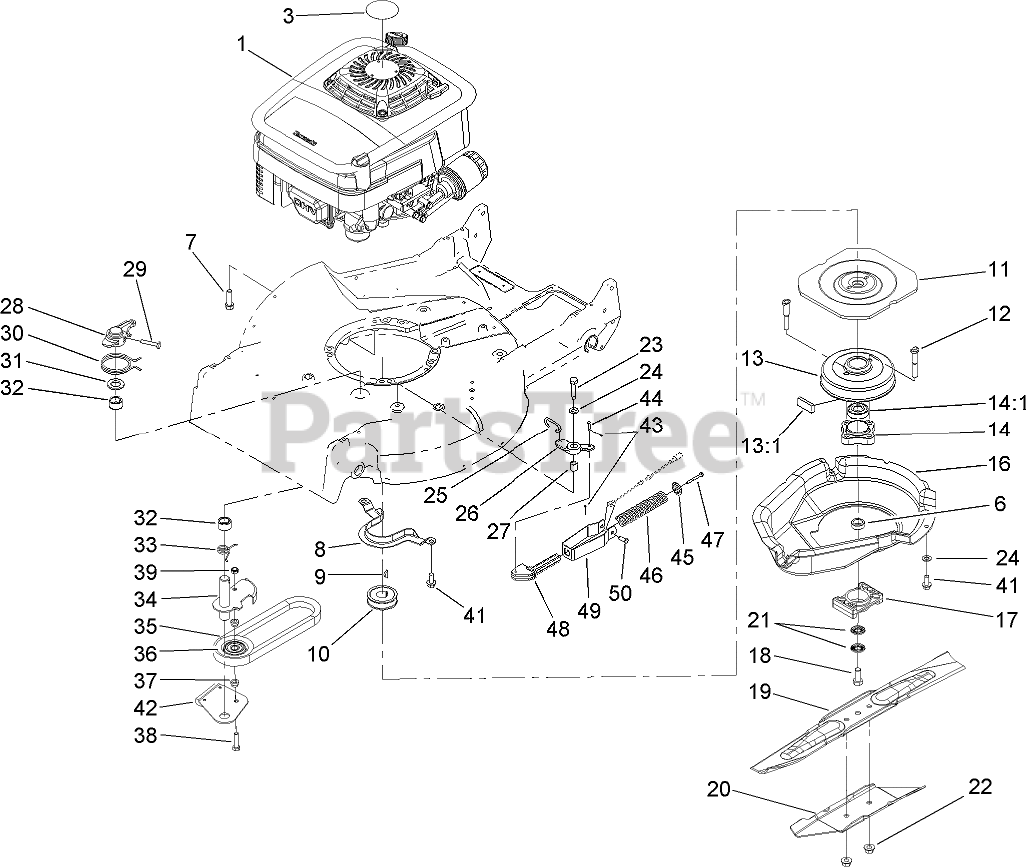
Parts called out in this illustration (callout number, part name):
1	ENGINE ASM
6	SPACER-SHAFT, OUTPUT
7	SCREW-TAPTITE
8	BRACKET-GUIDE, BELT
9	KEY-WOODRUFF
10	PULLEY-DRIVER
11	FLYWHEEL-BBC
12	BOLT-BLADE
13	BRAKE DRUM ASM
13:1	DAMPENER-VIBRATION
14	HUB ASM
14:1	BEARING-BALL
16	SHIELD
17	SPACER-BLADE
18	SCREW-HH
19	BLADE-21 INCH
20	STIFFENER-BLADE
21	WASHER-SPRING
22	NUT-LOCK
23	SCREW-HH
24	WASHER-PLAIN
25	LINK-CONTROL
26	BELLCRANK
27	SLEEVE-BELLCRANK
28	LEVER
29	SCREW-HH
30	SPRING-TORSION
31	WASHER
32	BEARING
33	SPRING-TORSION
34	ARM-IDLER
35	V-BELT
36	PULLEY-IDLER
37	SPACER-PULLEY, IDLER
38	SCREW-HH
39	NUT-LOCK, NI
41	SCREW-HWHTF
42	BRAKE PLATE ASM
43	PIN-COTTER
44	PIN-SPRING
45	RETAINER-SPRING
46	SPRING
47	SCREW-HWHTF
48	GUIDE-SPRING
49	BRACKET-SPRING
50	PIN-CABLE
